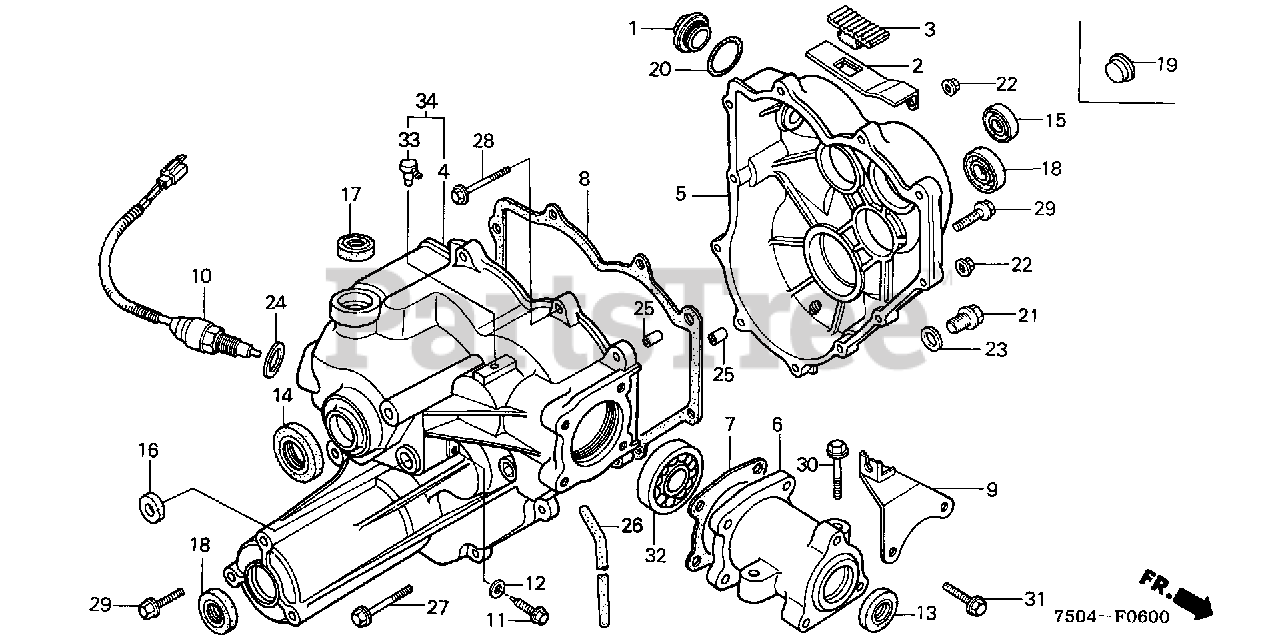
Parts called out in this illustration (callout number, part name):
1	CAP, VALVE ADJ.
2	STAY, TANK CUSHION RUBBER
3	RUBBER, TANK CUSHION
4	CASE, R. TRANSMISSION
5	CASE, L. TRANSMISSION
6	HOLDER, INPUT SHAFT
7	GASKET, INPUT SHAFT HOLDER (NOT AVAILABLE)
8	GASKET, TRANSMISSION CASE
9	HOLDER, CLUTCH CABLE
10	SWITCH ASSY., NEUTRAL
11	BOLT, SPECIAL (6MM)
12	WASHER A (6MM)
13	OIL SEAL (20X34X6)
14	OIL SEAL (27X38X7)
15	OIL SEAL (17X30X6) (NOK)
16	OIL SEAL (12X18X4)
16	OIL SEAL (12X18X5)
17	OIL SEAL (16X28X7)
18	OIL SEAL (25X34X7)
20	O-RING (30.8MM)
21	BOLT, DRAIN PLUG (12MM)
22	NUT, FLANGE (6MM)
23	WASHER, DRAIN PLUG (12MM)
24	WASHER, DRAIN PLUG (14MM)
25	PIN A, DOWEL (8X14) (YAMADA)
26	BULK HOSE, VACUUM (5X3000) (5X265)
27	BOLT, FLANGE (6X40)
28	BOLT, FLANGE (6X45)
29	BOLT, FLANGE (8X20)
30	BOLT, FLANGE (8X32)
31	BOLT, FLANGE (8X28)
32	BEARING, RADIAL BALL (6204)
